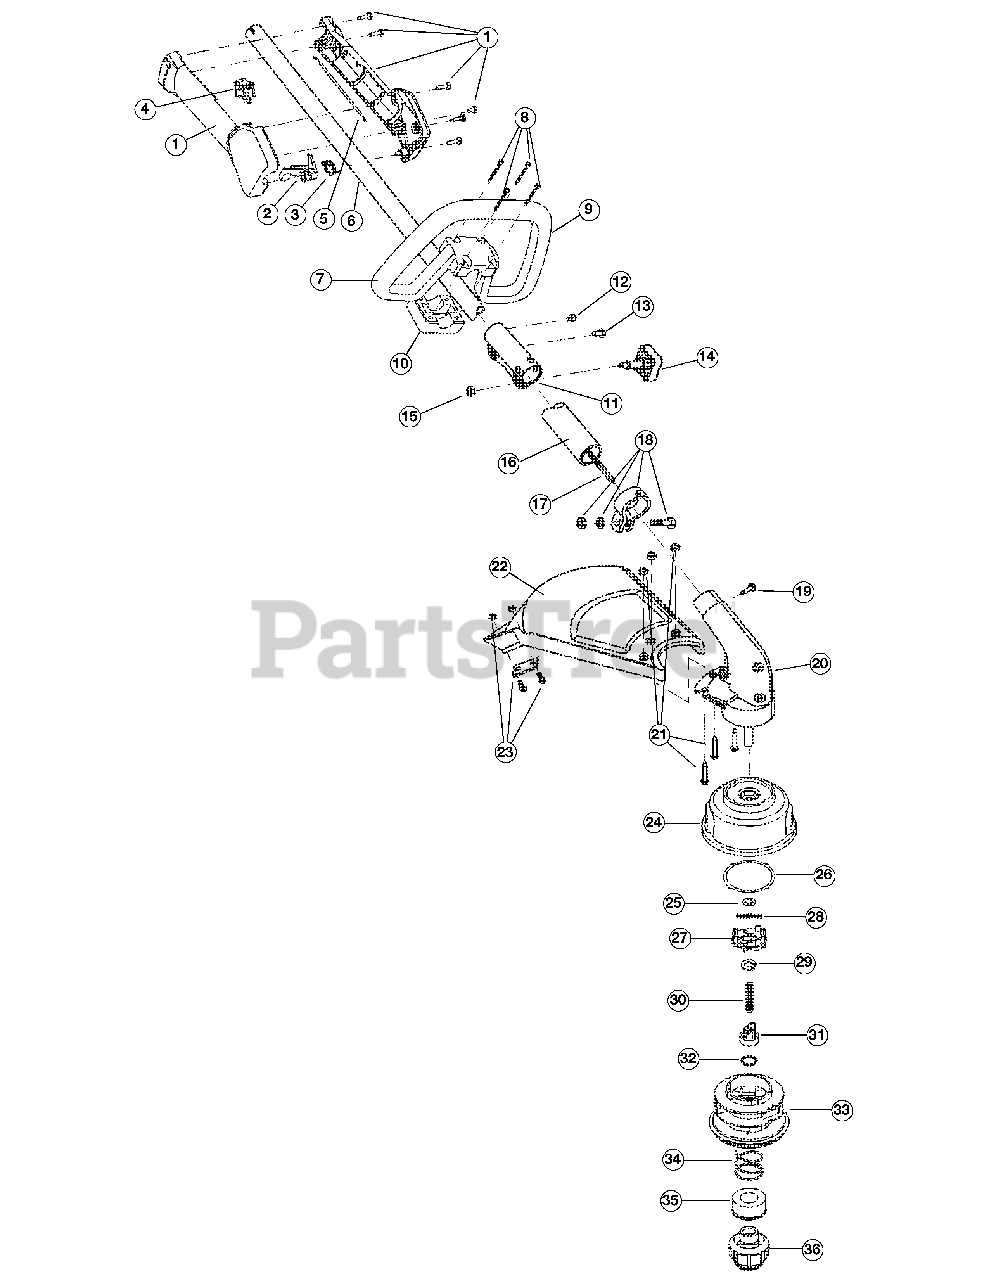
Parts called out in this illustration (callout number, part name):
1	Throttle Housing Assembly (includes 2-4)
2	Throttle Trigger
3	Throttle Trigger Spring
5	Throttle Cable Assembly
6	Upper Drive Shaft Housing Assembly
7	Deluxe D-Handle Assembly (includes 8-10)
9	Deluxe D-Handle
10	Bottom Clamp
11	Split Boom Coupler (includes 12-15)
14	Adjustment Knob (includes 15)
15	Knob Retaining Nut
16	Lower Drive Shaft Housing Assembly
17	Lower Flexible Drive Shaft
18	Lower Clamp Assembly (includes 19)
19	Anti-Rotation Screw
20	Gear Box Assembly
21	Shield Mounting Hardware
22	Shield Assembly (includes 23)
23	Blade Assembly
24	Outer Spool Assembly (includes 25)
26	Thrust Washer
28	Small Spring
33	Inner Reel
34	Large Spring
36	Bump Head Knob Assembly (includes 34 & 35)
